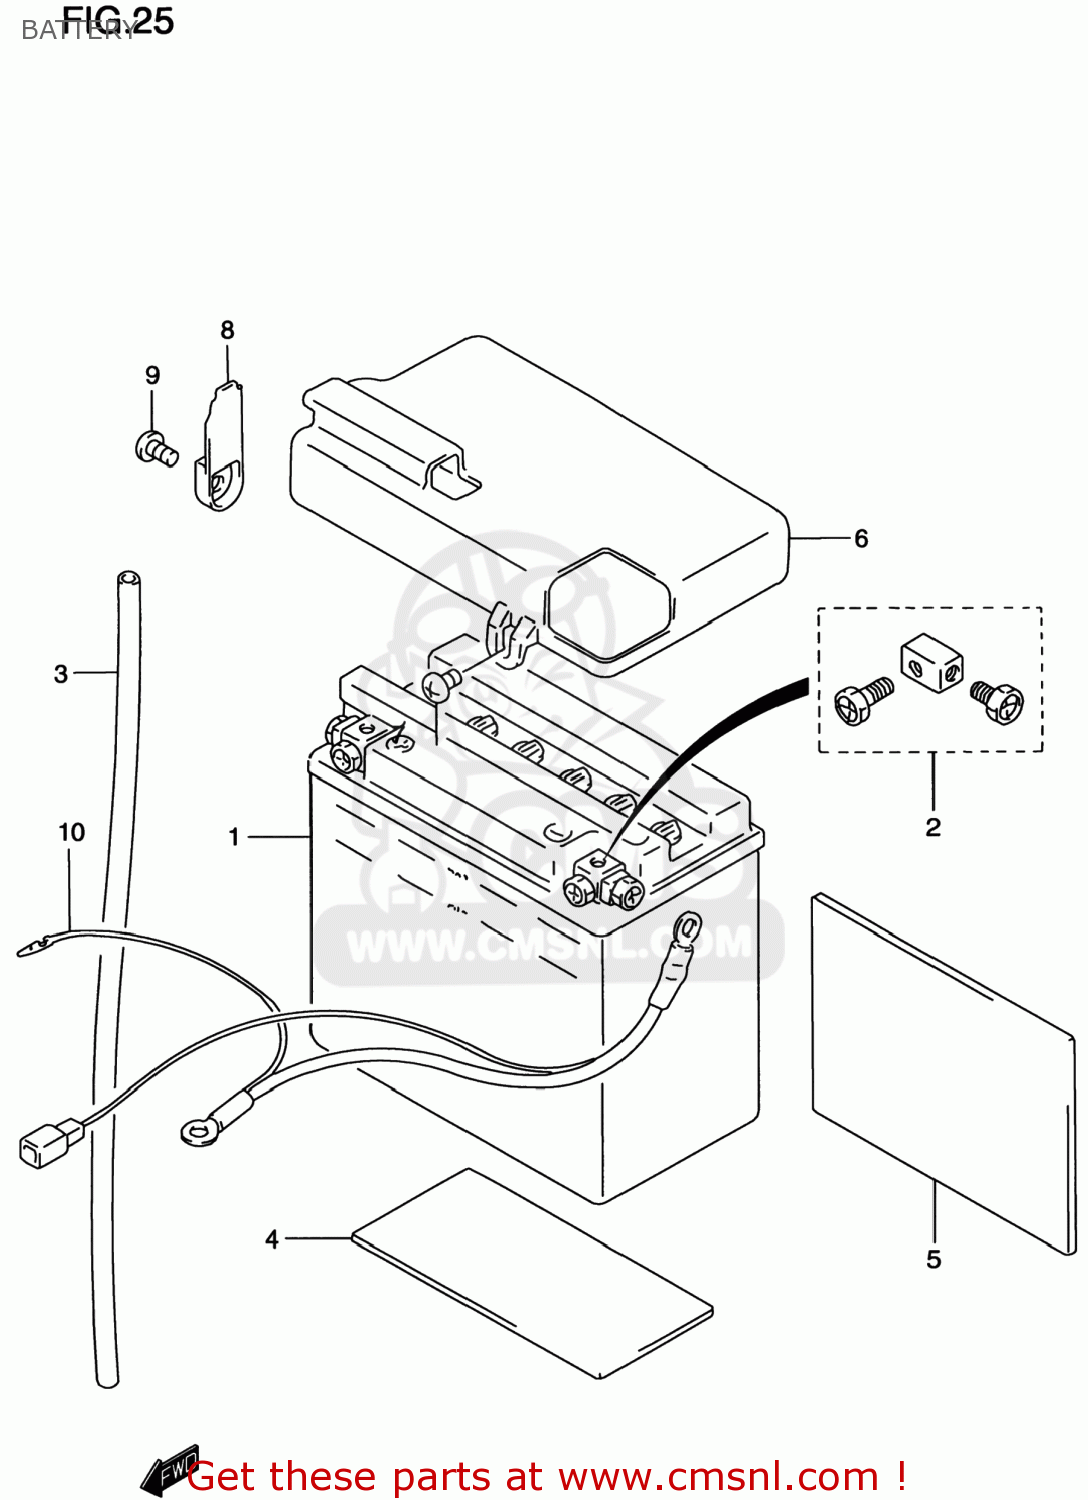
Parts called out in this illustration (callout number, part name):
1	BATTERY ASSY (12V)
2	BOLT SET,BATTERY TERMINAL
3	HOSE,BATTERY EXHAUST(L:780)
4	PROTECTOR(170X95X3.0)
5	PROTECTOR(80X80X2)
6	COVER,BATTERY UPR
7	SCREW
8	COVER,BATTERY TERMINAL
9	SCREW
10	WIRE,BATTERY MINUS LEAD
